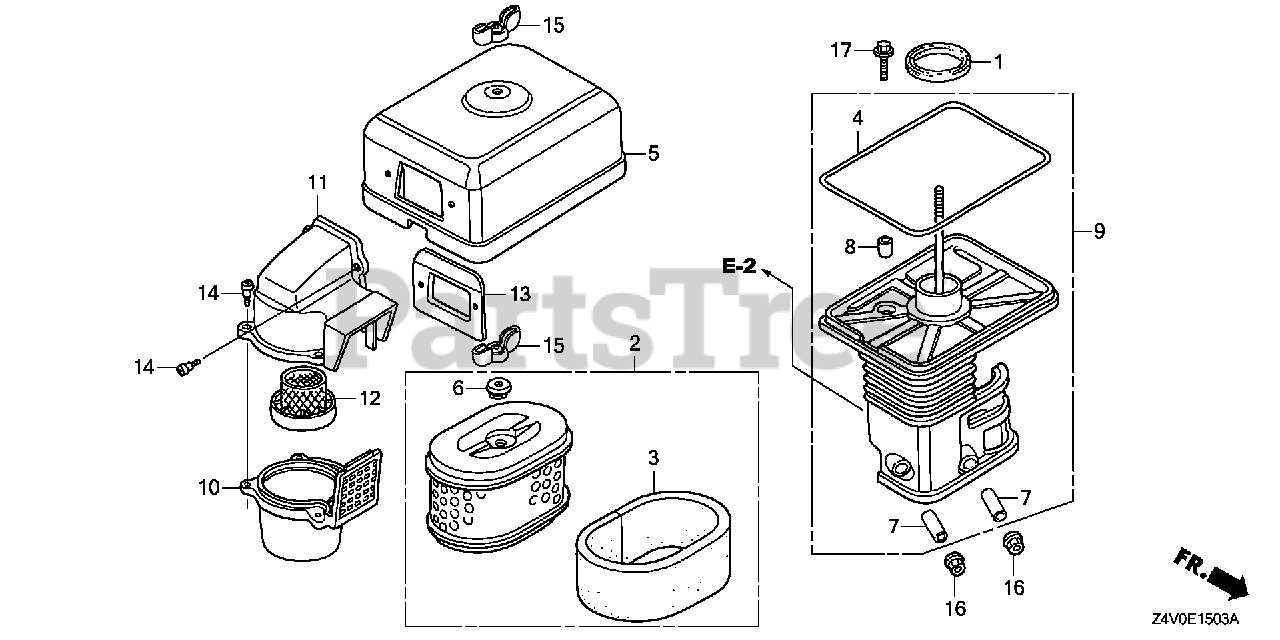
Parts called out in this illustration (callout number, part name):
1	GASKET, ELBOW
2	ELEMENT, AIR CLEANER (DUAL)
3	FILTER (OUTER)
4	GASKET, AIR CLEANER COVER
5	COVER, AIR CLEANER (CYCLONE)
6	GROMMET, AIR CLEANER
7	COLLAR, AIR CLEANER
8	COLLAR B, AIR CLEANER
9	ELBOW, AIR CLEANER
10	CASE, PRE AIR CLEANER
11	CAP, PRE AIR CLEANER
12	GUIDE, PRE AIR CLEANER
13	PLATE, PRE AIR CLEANER
14	BOLT, SPLASH GUARD
15	NUT, TOOL BOX SETTING
16	NUT, FLANGE (6MM)
17	BOLT, FLANGE (6X20)
